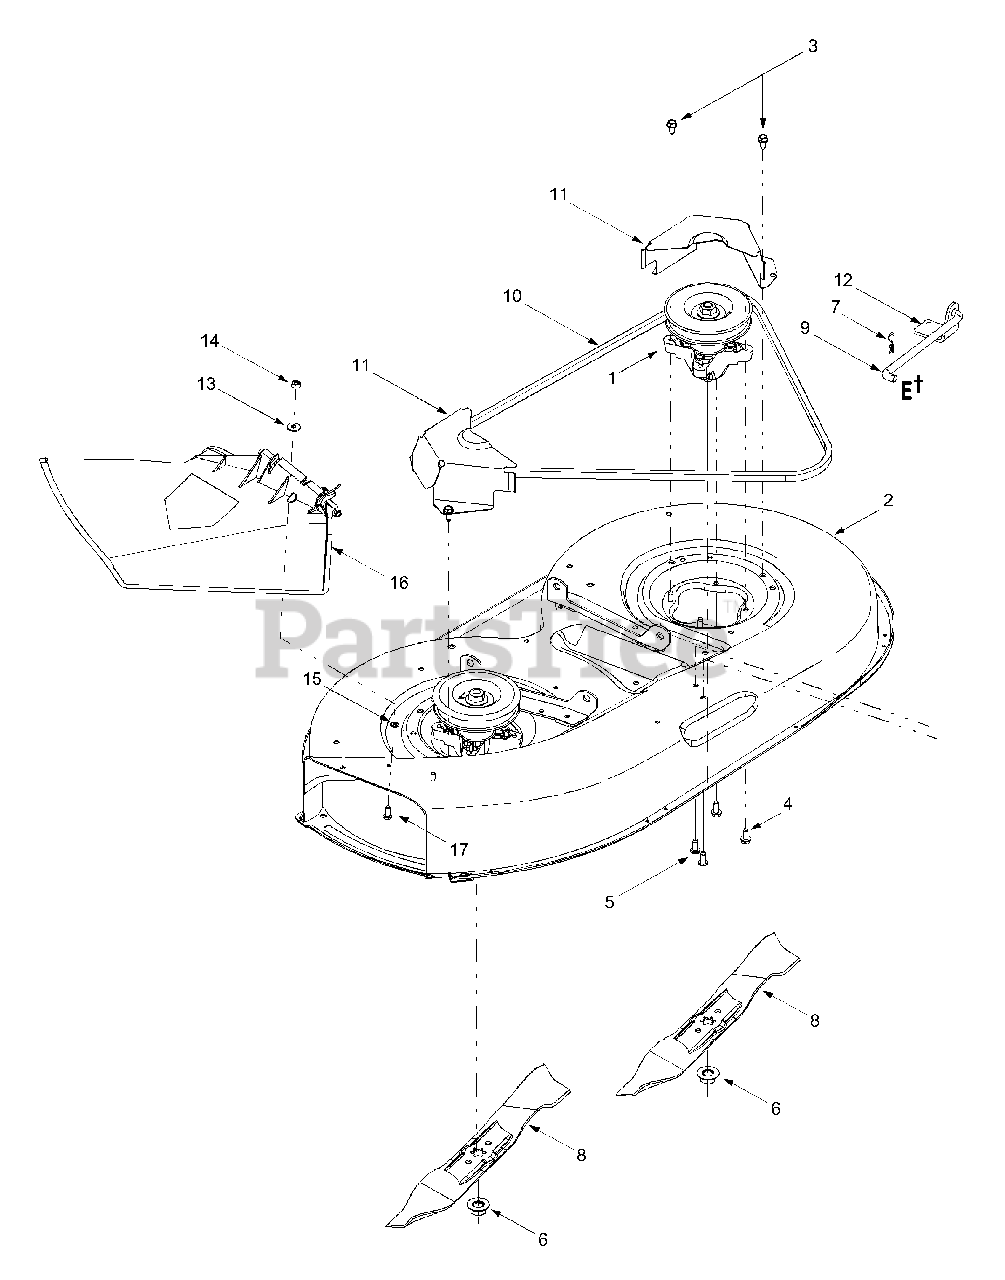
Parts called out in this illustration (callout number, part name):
1	Spindle Assembly
3	Self-tapping Screw, 5/16-12 x .75
4	Screw, 5/16-18 x .75
5	Self-tapping Screw, 5/16-18 x .75
6	Hex Flange Nut, 5/8-18
7	Internal Cotter Pin, .080 x 1.56
8	Blade, 19.38"
9	Deck Hanger Link/Anti-sway Rod
10	Deck Belt
13	Bell Washer, .265 x .75 x .062
14	Hex Nut, 1/4-20
15	Push Nut, 1/4
16	Discharge Chute Assembly
17	Hex Cap Screw:1/4-20 x .620
